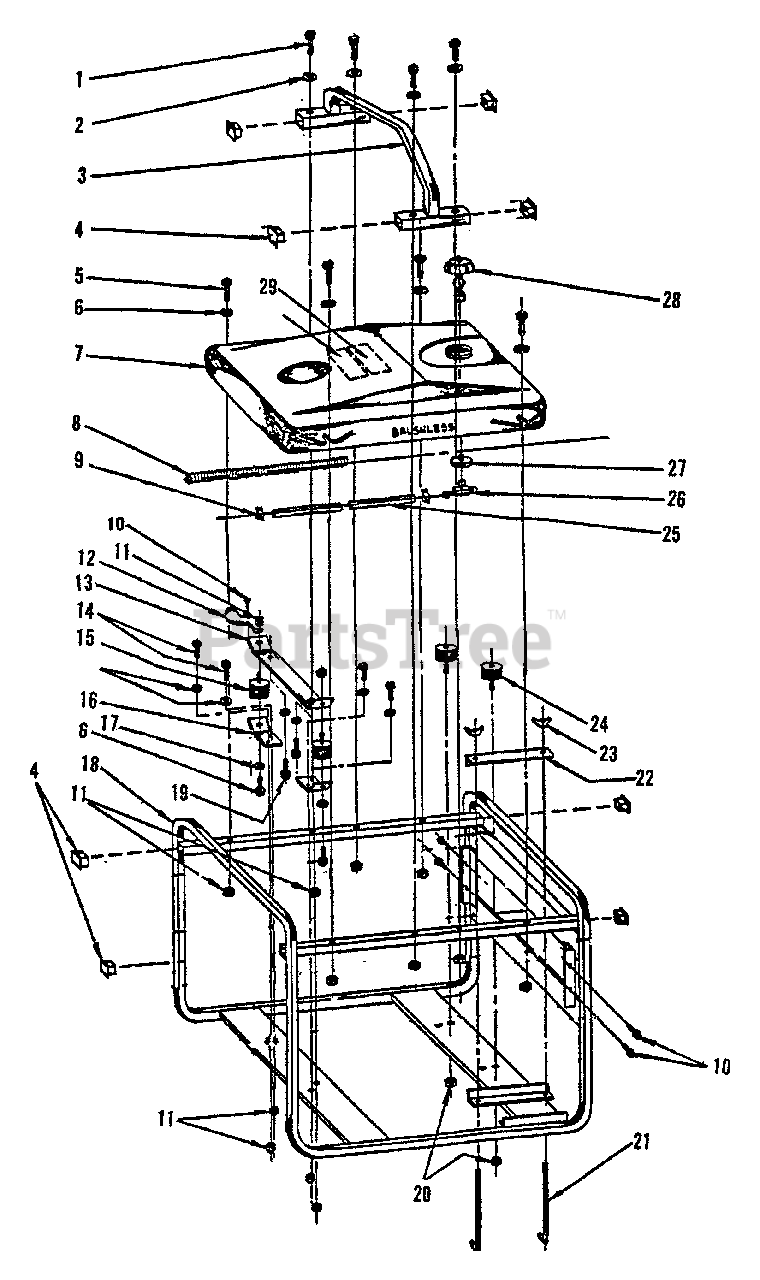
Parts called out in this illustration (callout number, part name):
1	5/16-18×2.5 HHS
2	LOCKWASHER - 5/16"
3	HANDLE, LIFT
4	PLUG, END
5	BOLT - 5/16-18×1-1/2"
6	WASHER, LOCK 5×16
7	TANK, FUEL - 6 GALLON
8	CONDUIT PIPE
9	CLAMP
10	SCREW - 10-24
11	LOCKNUT - 5/16-18
12	STRAP, GROUND
13	RAIL, FOCUS
14	5/16-18×7/8 HHS
15	ISOLATOR, VIBRATION
16	BRACKET, FOCUS
17	5/16-18×5/8 HHS
18	FRAME
19	5/16-18×3/4 HHS
20	LOCKNUT - 3/8-16
21	BOLT, BATTERY HOLD DOWN
22	BRACKET, BATTERY
23	WINGNUT - 1/4"
24	ISOLATOR, VIBRATION
25	LINE, FUEL - 24"
26	VALVE, FUEL TANK
27	GROMMET
28	CAP ASSY
29	LABEL - SAFETY
